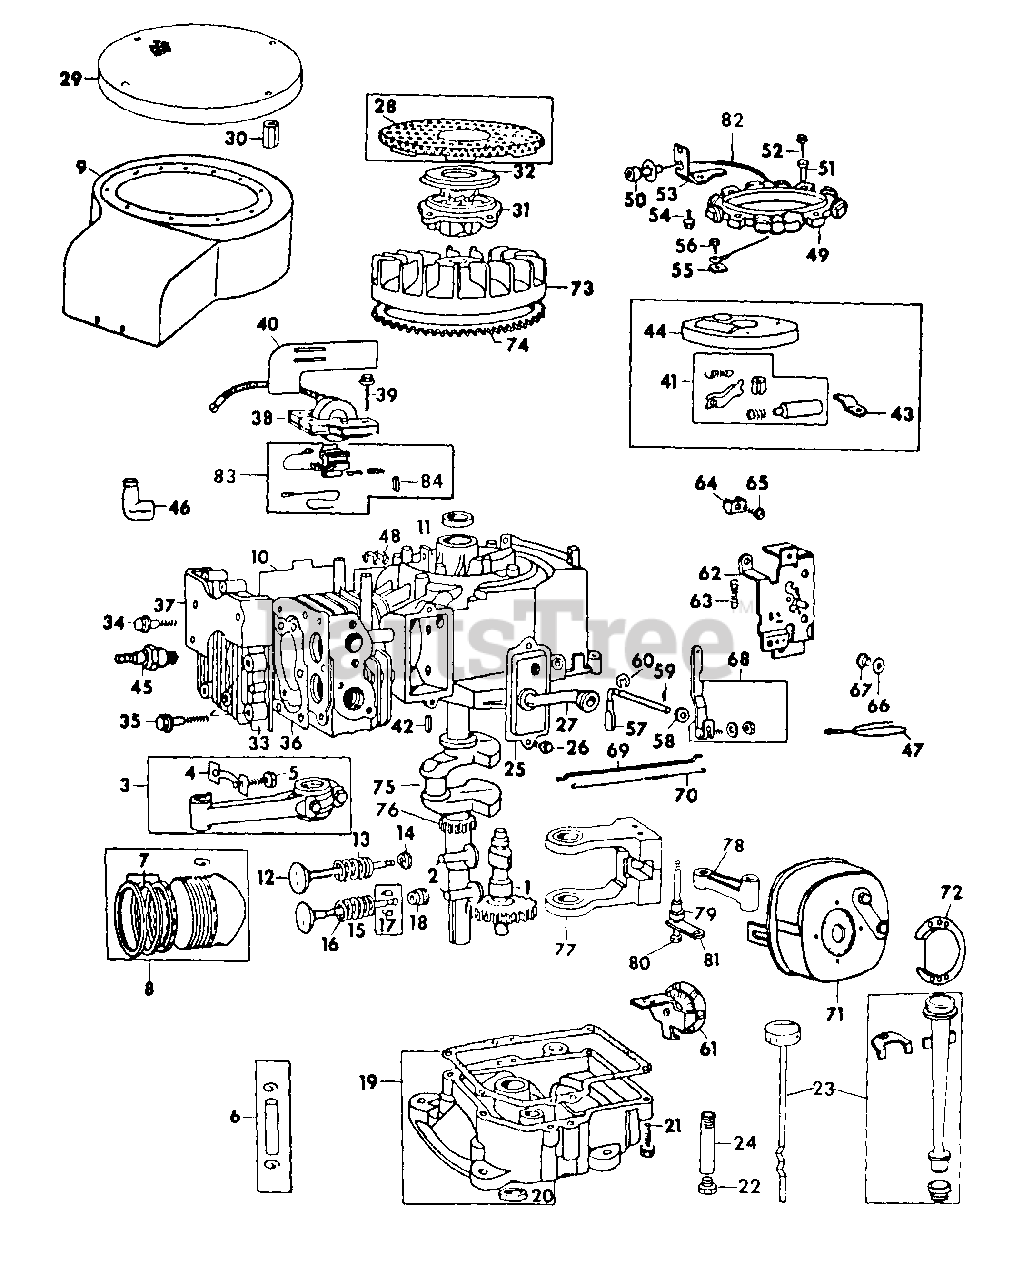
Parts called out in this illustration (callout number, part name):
1	CAMSHAFT
2	TAPPET, VALVE
3	ROD ASSY, CONNECTING STD
4	LOCK, SCREW HEAD
5	SCREW, CONNECTING ROD
6	PIN, PISTON - STD
7	RING SET. PISTON CHROME - STD
7	RING SET, PISTON - STD
8	PISTON ASSY, STD
9	HOUSING, BLOWER
10	SHIELD, CYLINDER
11	SEAL, OIL TOP
12	VALVE, INTAKE
13	SPRING, INTAKE VALVE
14	RETAINER, INTAKE VALVE
15	VALVE, EXHAUST
16	SPRING, EXHAUST VALVE
17	RETAINER, ROTO-COIL
18	ROTO-COIL, EXHAUST VALVE
19	SUMP, OIL
20	SEAL, OIL BOTTOM
21	SCREW, SUMP MOUNTING
22	PLUG, 1/4-18 AUTOMOTIVE HEX-HD PIPE -OIL DRAIN-
23	GAUGE ASSY, OIL LEVEL
24	PIPE, OIL DRAIN
25	BREATHER, VALVE CHAMBER
26	SCREW, BREATHER MOUNTING
27	TUBE, BREATHER
28	SCREEN, REWIND STARTER
29	SCREEN BLOWER HOUSING
30	SPACER BLOWER HOUSING SCREW
31	HOUSING, REWIND STARTER -CLUTCH-
32	COVER, HOUSING
33	HEAD, CYLINDER
34	SCREW, CYLINDER HEAD - SHORT
35	SCREW, CYLINDER HEAD - LONG
36	GASKET, CYLINDER HEAD
37	COVER, CYLINDER HEAD
38	ARMATURE ASSY, MAGNETO
39	SCREW, ARMATURE MOUNTING
41	KIT, BREAKER POINT & CONDENSER
42	KEY, FLYWHEEL
43	CLAMP, CONDENSER
44	COVER, BREAKER POINT
45	PLUG, RESISTOR SPARK -CHAMPION-
46	ELBOW, SPARK PLUG INSULATOR
47	WIRE ASSY, GROUND
49	STATOR W/BRACKET, ALTERNATOR
51	BUSHING, STATOR
52	SCREW, STATOR MOUNTING
53	BRACKET, FUSE
54	SCREW, BRACKET MOUNTING
56	SCREW, 8-32 X 3/8 HEX-HD
57	CRANK, GOVERNOR
58	WASHER, GOVERNOR CRANK
59	COTTER, GOVERNOR CRANK
60	RETAINER, GOVERNOR CRANK
61	GEAR, GOVERNOR
62	PLATE, GOVERNOR
63	SPRING, GOVERNOR
64	CLAMP, CASING
65	SCREW W/LOCKWASHER, HEX-HD
66	WASHER, INSULATING
67	COLLAR, INSULATING
68	LEVER ASSY, GOVERNOR
69	LINK, GOVERNOR
70	SPRING, GOVERNOR LINK
71	MUFFLER
73	FLYWHEEL
73	FLYWHEEL AND RING GEAR ASSY
74	GEAR, FLYWHEEL RING
75	CRANKSHAFT
76	GEAR, TIMING
77	COUNTERWEIGHT ASSY
78	LINK, COUNTERWEIGHT
79	SPACER, COUNTERWEIGHT
80	BOLT, COUNTERWEIGHT
81	SHIM, SCREW HEAD
82	CABLE ASSY, DIODE AND CONNECTOR
83	MODULE, MAGNETRON IGNITION KIT
84	KEY, FLYWHEEL
